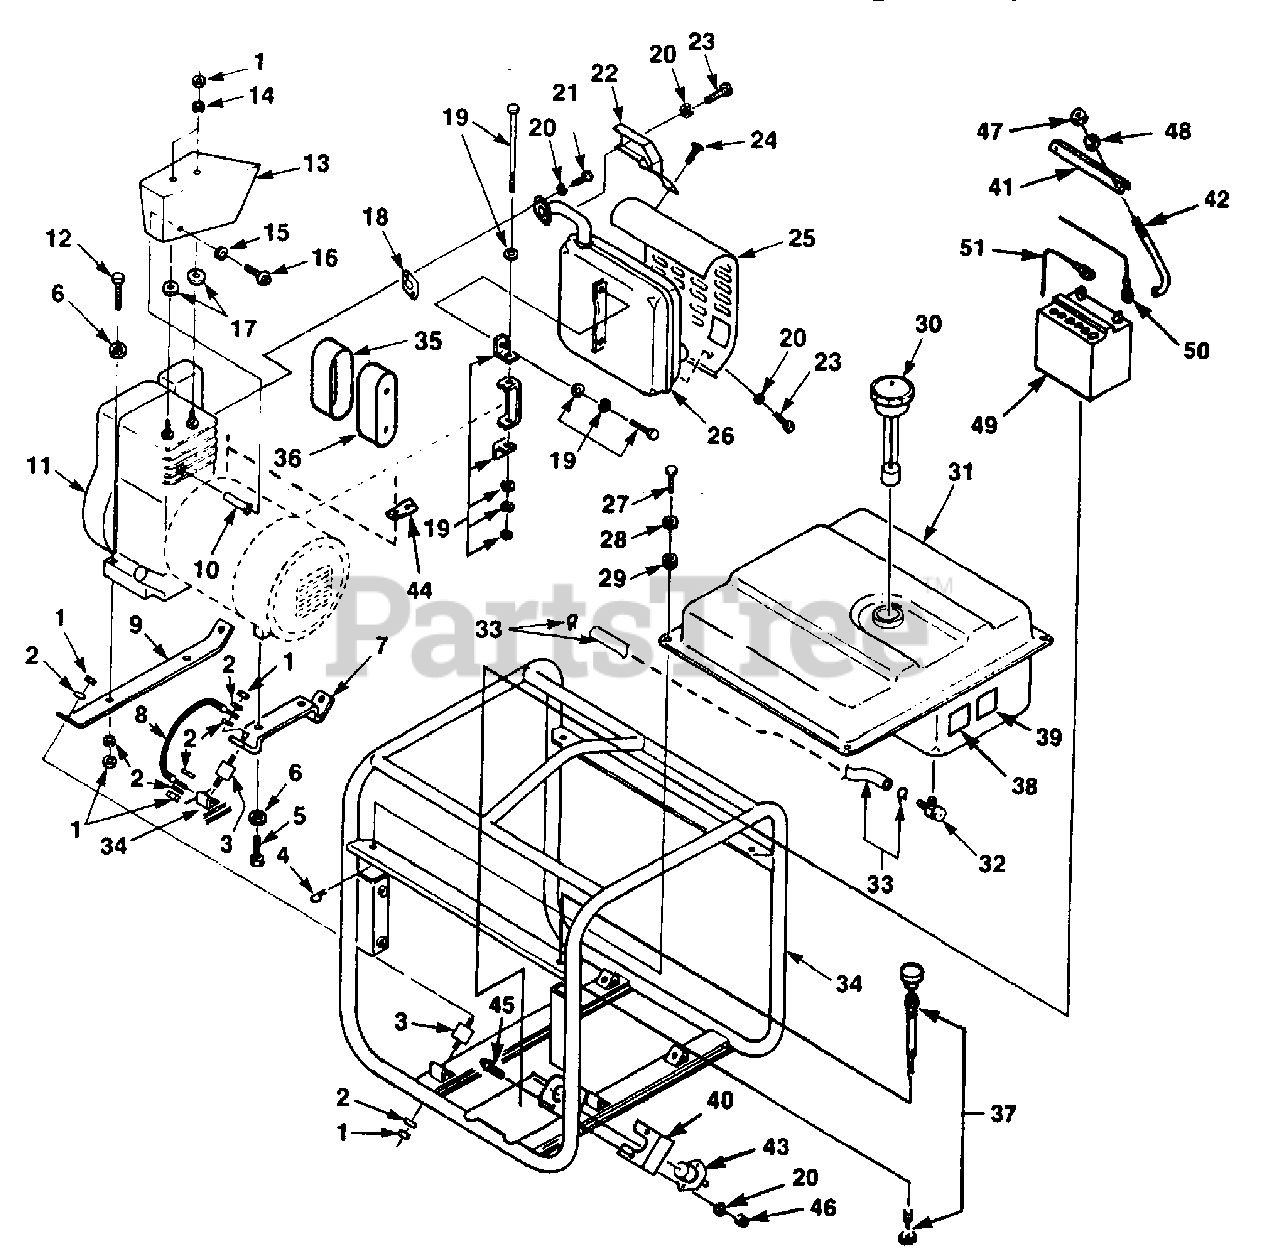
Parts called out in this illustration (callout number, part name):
1	NUT- 5/16-18"
2	WASHER-Lock int. 5/16"
3	ISOLATOR- Vibration
4	PIN- Cotter hair
5	SCREW- Hex tapping 5/16-18 x 1"
6	WASHER- Lock int. 5/16"
7	SUPPORT- Generator
8	GROUND STRAP
9	SUPPORT- Engine
10	SPACER (HG3500)
12	SCREW- Hex hd 5/16-18 x 1 3/4"
13	DEFLECTOR- Air (HG3500)
14	WASHER- Lock
15	WASHER-Flat #10 (HG3500)
16	SCREW 10-24 x 1 1/2" (HG3500)
17	WASHER- Flat 5/16" (HG3500)
18	GASKET- Muffler
19	MUFFLER BRACKET KIT
20	WASHER- Lock 1/4"
21	SCREW- Cap hex sock 1/4-20 x 1/16"
22	SHIELD- Exhaust
23	SCREW- Hex cap 1/4-20 x 1 1/8"
24	SCREW- Tap pan hd #8-18 x 3/8"
25	SHIELD- Muffler
26	MUFFLER
27	PIN- Clevis
28	WASHER- Flat 1/4"
29	GROMMET- Isolator
30	CAP- Fuel
31	FUEL TANK
32	VALVE- Fuel
33	FUEL LINE ASSEMBLY (See Note 2)
34	ROLL CAGE(HG3500)
35	PREFILTER
37	CHOKE- Cable (HGE3500)
38	DECAL- Fuel valve
39	DECAL- Caution
40	COVER- Switch (HGE3500)
41	STRAP- Battery (HGE3500)
42	BOLT- Battery (HGE3500)
43	SWITCH- Starter (HGE3500)
44	BRACKET- Choke (HGE3500)
45	SCREW- Hex hd. 1/4-20 x 1/2" (HGE3500)
46	NUT- Hex 1/4-20" (HGE3500)
47	NUT- Hex #10 (HGE3500)
48	WASHER- Lock (HGE3500)
49	BATTERY (HGE3500)
50	CABLE- Battery (-) (HGE3500)
51	CABLE- Battery (+) (HGE3500)
